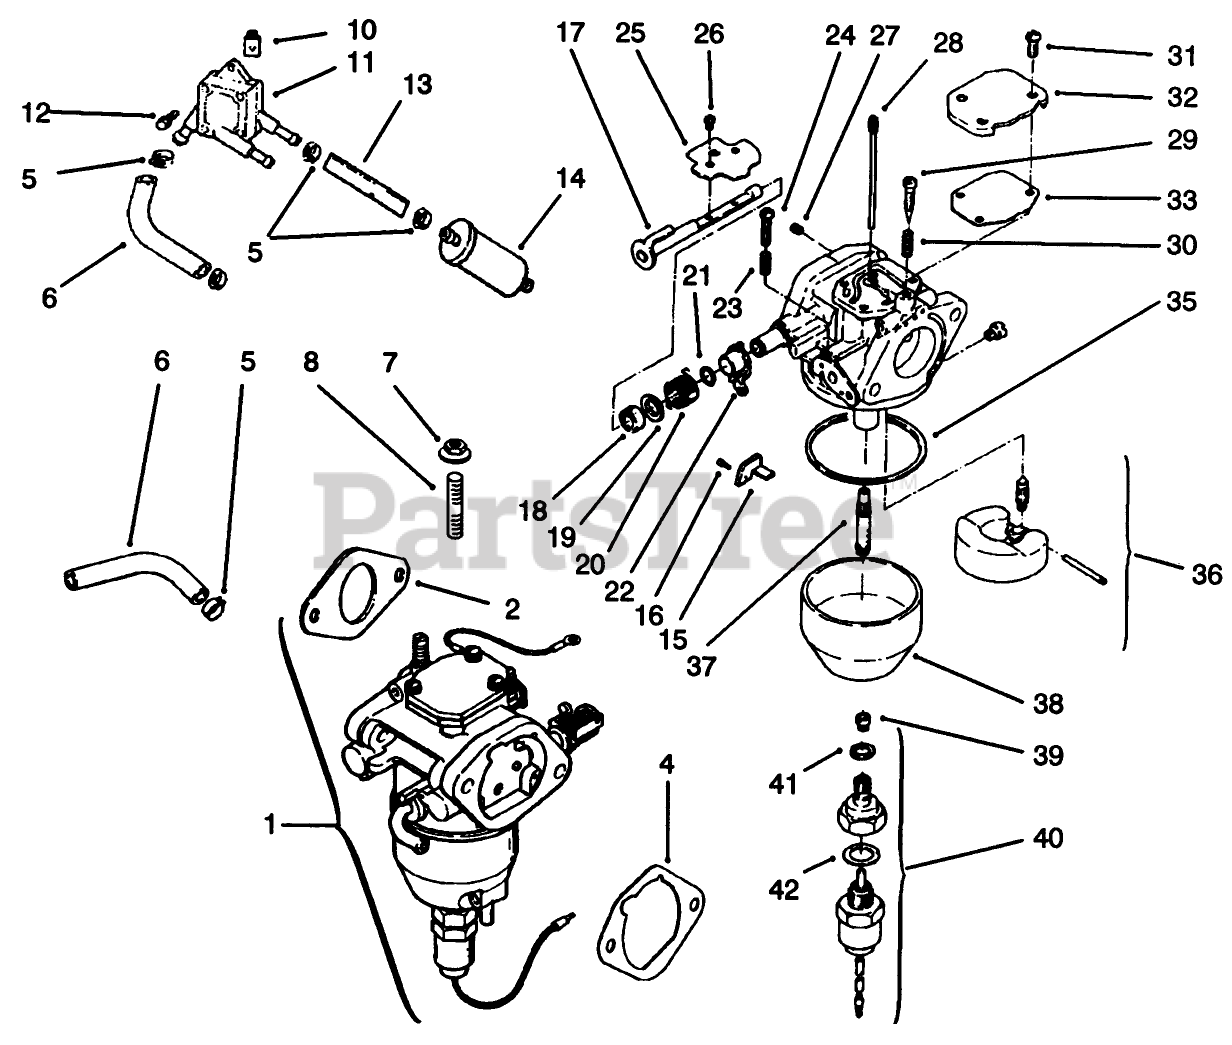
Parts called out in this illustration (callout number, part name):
2	Gasket-Carburetor (Only On: 72103)
4	Gasket-A/C Base (Only On: 72103, 72083)
5	Clamp
6	Line-Fuel 10 1/2" (Only On: 72103, 72083)
8	Stud M6x1.0x95 (Only On: 72103, 72083)
11	Pump-Fuel
13	Line-Fuel 3 1/2" (Only On: 72103)
14	Filter-Fuel (Only On: 72042,72043,72062,72063)
15	Bracket-Throttle Stop (Only On: 72103, 72083)
16	Screw M2.5X45X5.5 (Only On: 72103)
17	Shaft-Choke (Only On: 72103, 72083)
18	Washer (Only On: 72103, 72083)
19	Collar-Choke (Only On: 72103, 72083)
20	Spring-Choke Return (Only On: 72103, 72083)
21	Ring-Choke Lever (Only On: 72103)
22	Lever-Choke (Only On: 72103)
23	Spring-Throttle Screw (Only On: 72103, 72083)
24	Screw-Throttle Adjust (Only On: 72103, 72083)
25	Valve-Choke
26	Screw-Throttle Shaft (Only On: 72103, 72083)
27	Jet-Air Bleed (Only On: 72103)
28	Jet-Slow (Only On: 72103)
29	Screw-Idle Adjust (Only On: 72103, 72083)
30	Spring-Idle Adjust Screw (Only On: 72103)
31	Screw (Only On: 72103)
32	Cover-Passage (Only On: 72103, 72083)
33	Gasket-Passage Cover (Only On: 72103, 72083)
35	Gasket-Float Chamber (Only On: 72103)
36	Kit-Float Repair (Only On: 72103)
37	Nozzle-Main (Only On: 72103,72083)
38	Chamber-Float (Only On: 72103)
39	Jet-Main (Only On: 72103)
40	Kit-Solenoid INC 41-42 (Only On: 72103, 72083)
41	Gasket-Chamber Screw (Only On: 72103)
42	Gasket-Solenoid (Only On: 72103, 72083)
